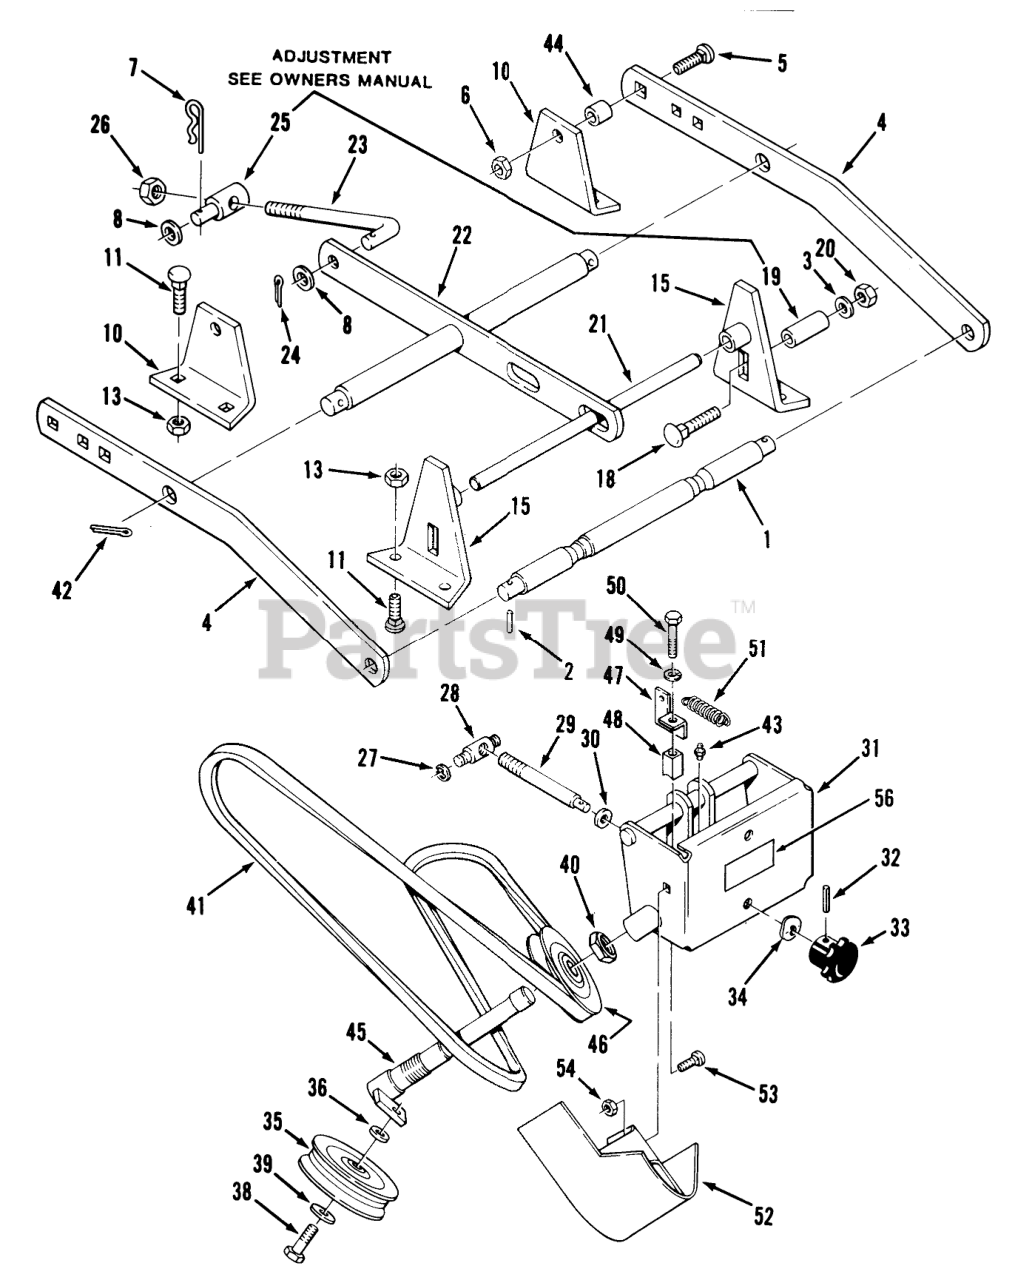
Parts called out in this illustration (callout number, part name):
1	Shaft
3	Washer
4	Bar-Draft
5	Bolt
6	LOCKNUT-FLANGE
7	Hairpin
8	Washer
10	Rear Deck Bracket
11	BOLT-CARR
13	NUT
15	Front Deck Bracket
18	BOLT-CARR
19	SPACER
20	Nut
21	Front Shaft
22	Leveler
23	ROD LEVELER
24	Cotter Pin
25	TRUNION
26	Nut
27	RING-RETAINING
28	TRUNNION-DOUBLE
29	ROD ADJ
30	Washer
31	Front Idler Support
32	PIN-ROLL
33	KNOB-ADJUSTMENT
34	WASHER-SPRING
35	PULLEY-FLAT IDLER
36	SPACER
38	SCREW-HH
39	Washer
40	Nut
41	BELT-103" A SECTION
42	PIN-COTTER
43	Grease Zerk
44	SPACER
45	ASS'Y-IDLER ARM
46	Pulley-V
47	Bracket
48	BLOCK-GUIDE
49	Lockwasher
50	Bolt
51	SPRING-BRAKE
52	Cover
53	Bolt
54	Nut
56	DECAL-BELT INSTALL
